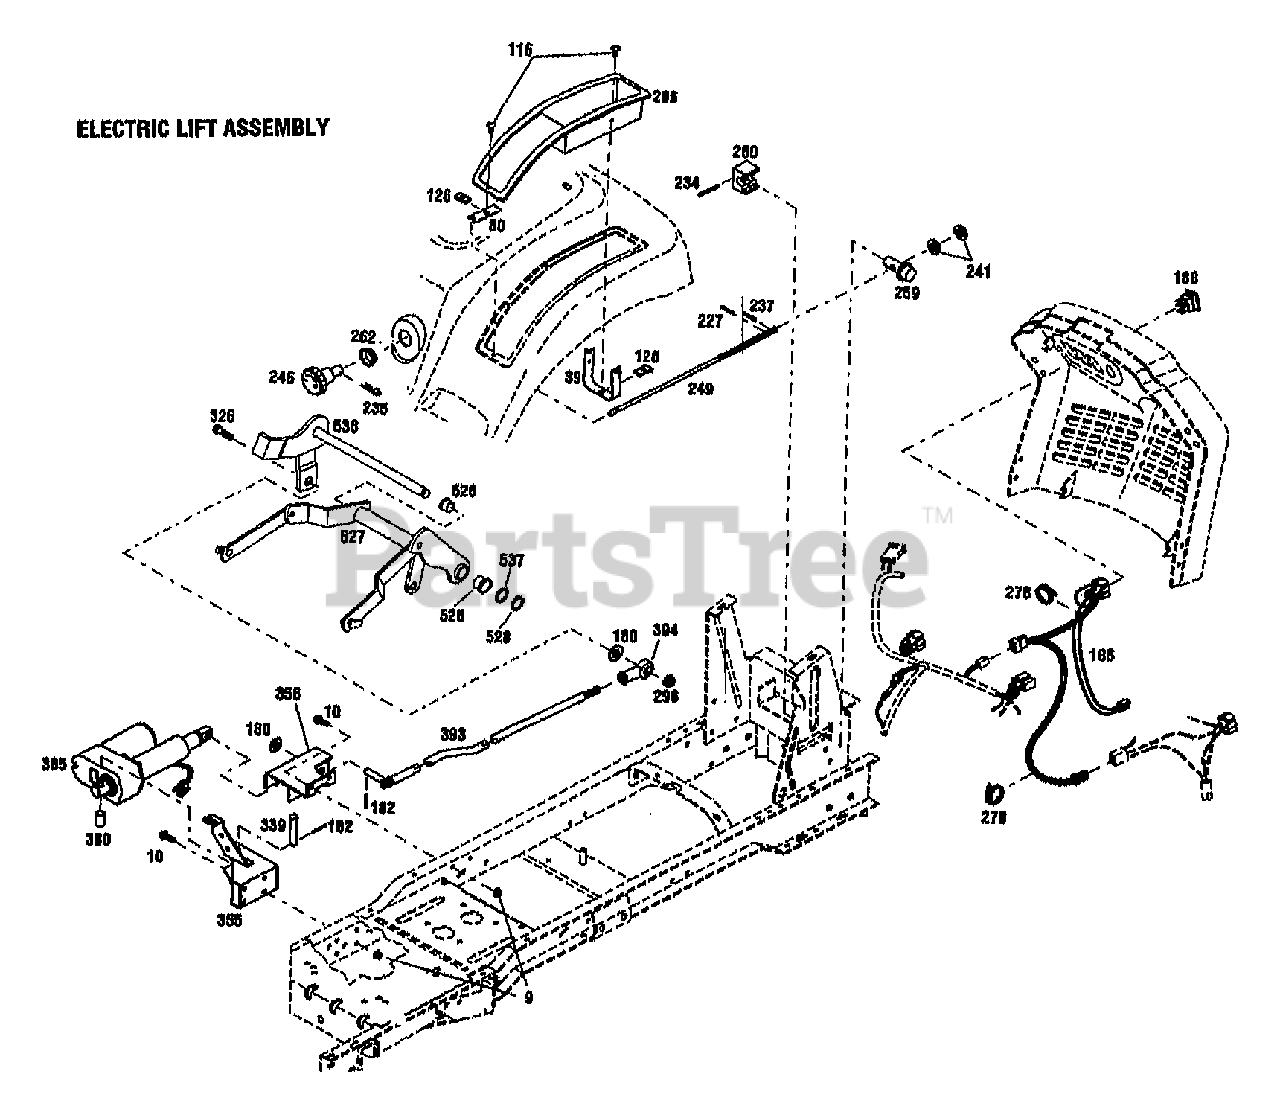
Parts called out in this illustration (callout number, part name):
9	NUT-HFLK 5/16-18 ZP
10	SCR-HHC 5/16-18X.75 GR 5 ZP
39	RETAINER-UTILITY BOX
80	RETAINER-UTILITY BOX
116	SCR-1/4-20X5/8
126	SPEED NUT-1/4-20
180	WASHER-1.06X.531X.1 ZP
182	PIN-COTTER .120X1.00 ZP
186	HARNESS-ACTUATOR
188	SWITCH-ROCKER
227	PIN-COTTER .125 X .75 ZP
234	PIN-DRIVE
235	PIN-HITCH
237	PIN-ROLL .156X1.0
246	KNOB-HEIGHT ADJUST
249	KIT-SVC SCR HGT ADJ
259	BLOCK-HEIGHT ADJUST
260	COLLAR-HEIGHT ADJUST
262	GROMMET-SNAP BUSHING
278	TIE-CABLE NYLON BLACK
285	UTILITY BOX
326	SCR-SPECIAL 1/2-13X1 1/2
339	PIN-CLEVIS .5X2.75
355	SUPPORT-FRONT
356	SUPPORT-REAR
393	ROD-LIFT
394	ROD-END
528	RING-RETAINING EXT .694 ID
537	WASHER-1.25X.765X.049
